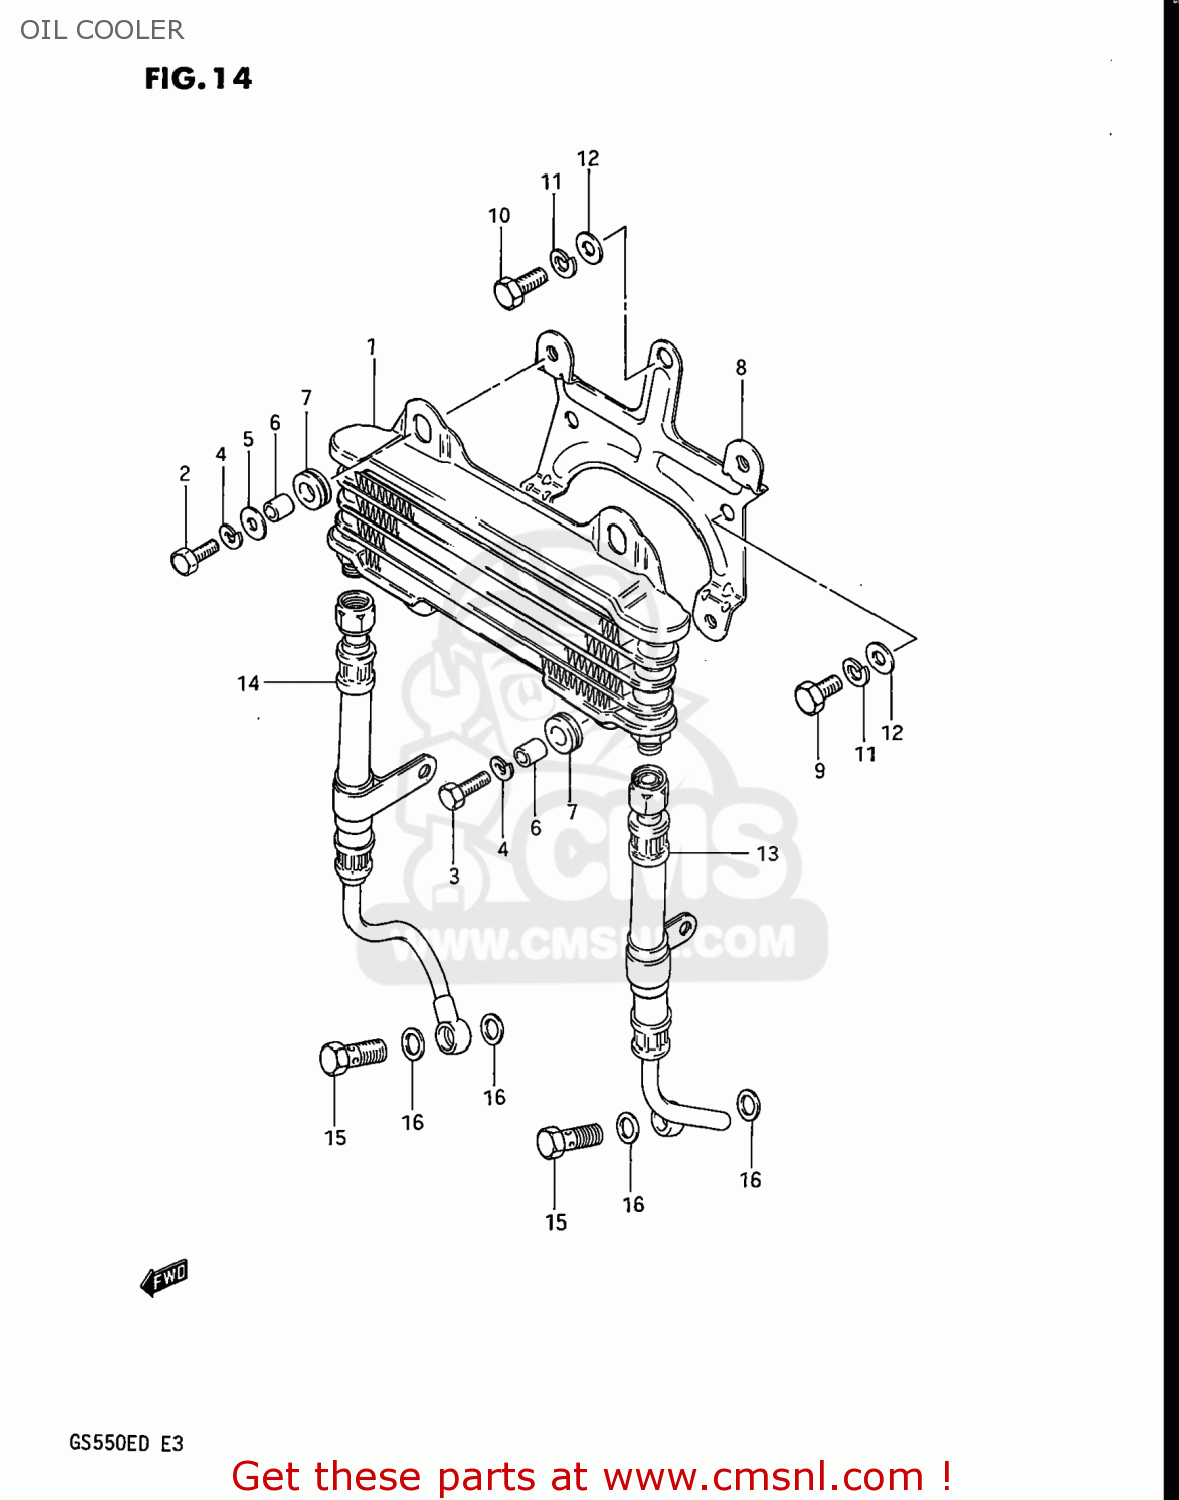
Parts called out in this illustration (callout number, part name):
1	COOLER ASSEMBLY,ENGINE OIL
2	BOLT
3	BOLT
4	LOCK WASHER
5	WASHER (6.5X18X1.6)
6	SPACER (6.8X10X10)
7	CUSHION
8	BRACKET,OIL COOLER
9	BOLT
10	BOLT
11	LOCK WASHER
12	WASHER,8.5X16X
13	HOSE,ENGINE OIL,LEFT
14	HOSE,ENGINE OIL,RIGHT
15	BOLT UNION
16	GASKET(14X20X1.5) (NAS)
